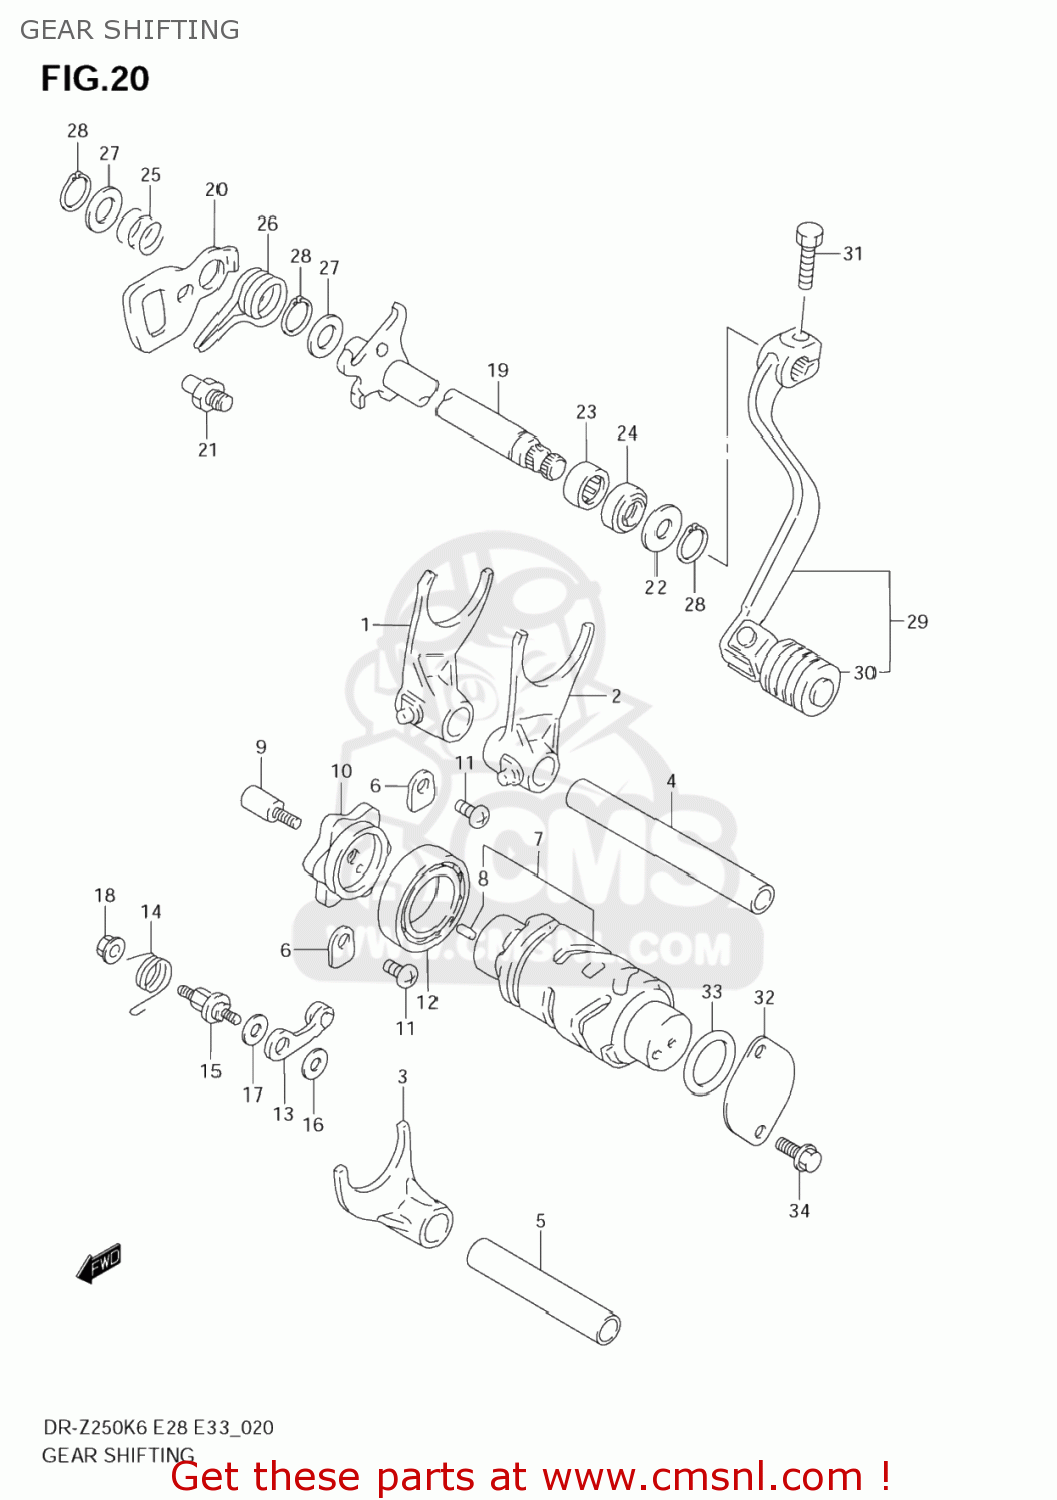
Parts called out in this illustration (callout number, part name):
1	FORK,GEAR SHIFT NO.1
2	FORK,GEAR SHIFT NO.2
3	FORK,GEAR SHIFT NO.3
4	SHAFT,GEAR SHIFT FORK(L:95)
5	SHAFT,GEAR SHIFT FORK(L:70)
6	RETAINER
7	CAM,GEAR SHIFT
8	PIN
9	PIN,SHIFT CAM DRIVEN GEAR
10	PLATE,GEAR SHIFT CAM
11	BOLT(6X12)
12	BEARING
13	STOPPER,GEAR SHIFT CAM
14	SPRING,SHIFT CAM STOPPER
15	SUPPORT,CAM STOPPER ARM
16	WASHER
17	WASHER
18	NUT
19	SHAFT,GEAR SHIFT
20	PLATE,GEAR SHIFT CAM DRIVE
21	STOPPER,GEAR SHIFT ARM
22	WASHER
23	BEARING(14X20X12)
24	SEAL,OIL(14X22X6)
25	SPRING
26	SPRING
27	SHIM(14X22X1)
28	CIRCLIP
29	LEVER ASSY,GEAR SHIFT
30	RUBBER,GEAR SHIFT PEDAL
31	BOLT
32	CAP,GEAR SHIFT CAM PIVOT
33	O RING(D:2.4,ID:26.2)
34	BOLT
